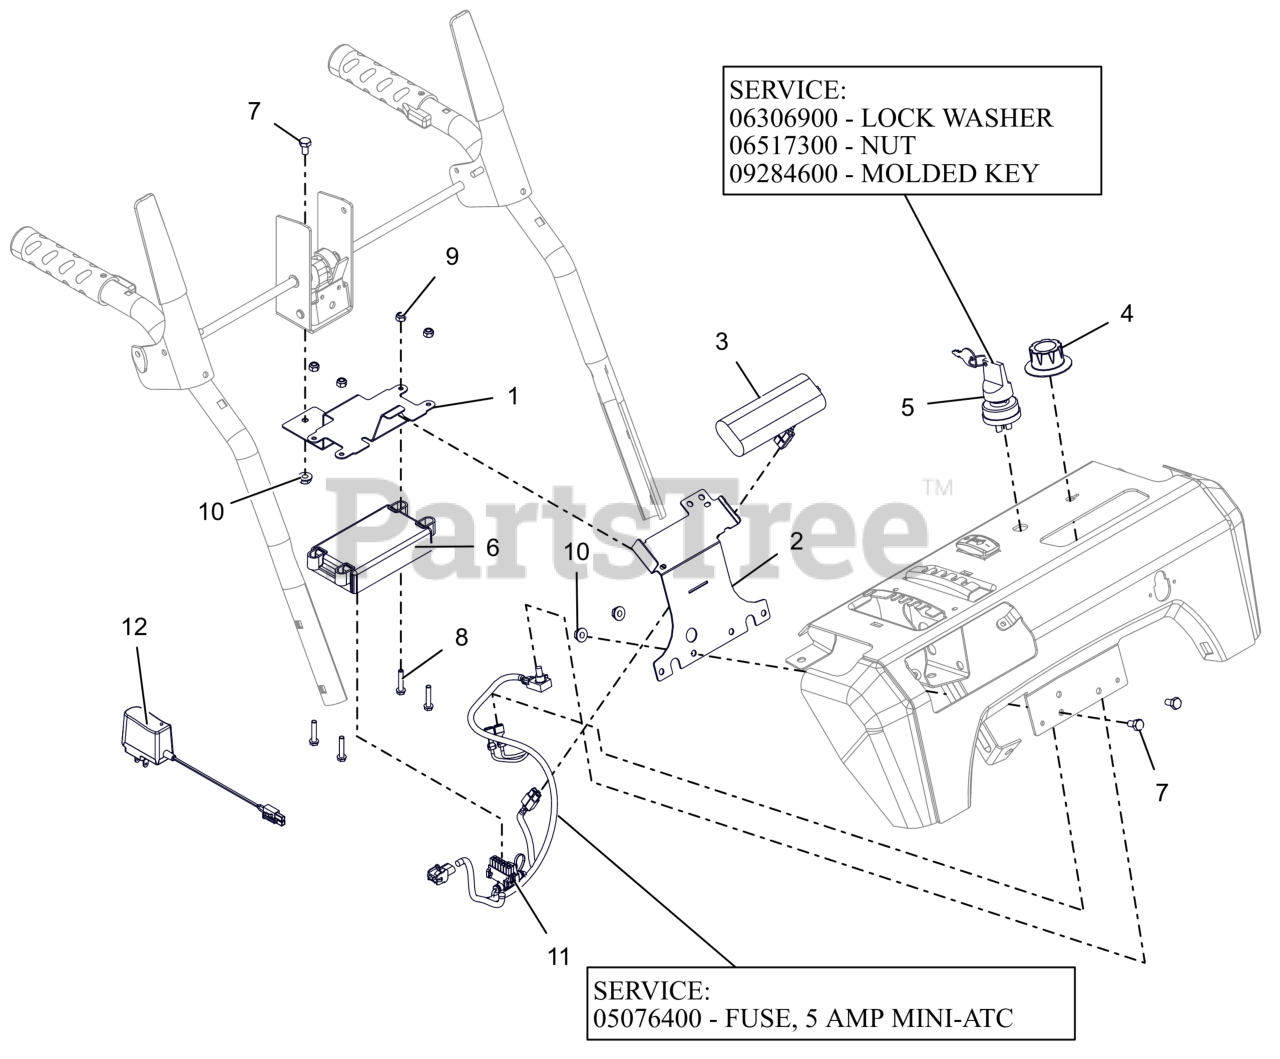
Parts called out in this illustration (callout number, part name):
1	BRACKET, ENGINE EFI-LCT LOWER
2	BRACKET, ENGINE EFI-LCT UPPER
3	BATTERY, SNOW EFI - 7.2V
4	KNOB, CONTROL - 2.063 ID
5	IGNITION SWITCH ASM - 2 POS
5	WSHR-LK-INT .625X.045 YWZC
5	NUT-PANEL .625-32 GRECO
5	KEY W/ SHIELD
6	ECU, AX369 EFI
7	BLT,HEX .25-20X.50 G5 ZCC
8	BLT, HWH #10-24X1.00 ZCC
9	NUT-LK-NYL #10-24 G2 ZCC
10	NUT-LK-TOP-FLG .250-20 GF ZCC
11	HARNESS,WIRE - EFI ECU
11	FUSE, 5 AMP MINI-ATC
12	CHARGER, BATTERY - EFI 7.2V
